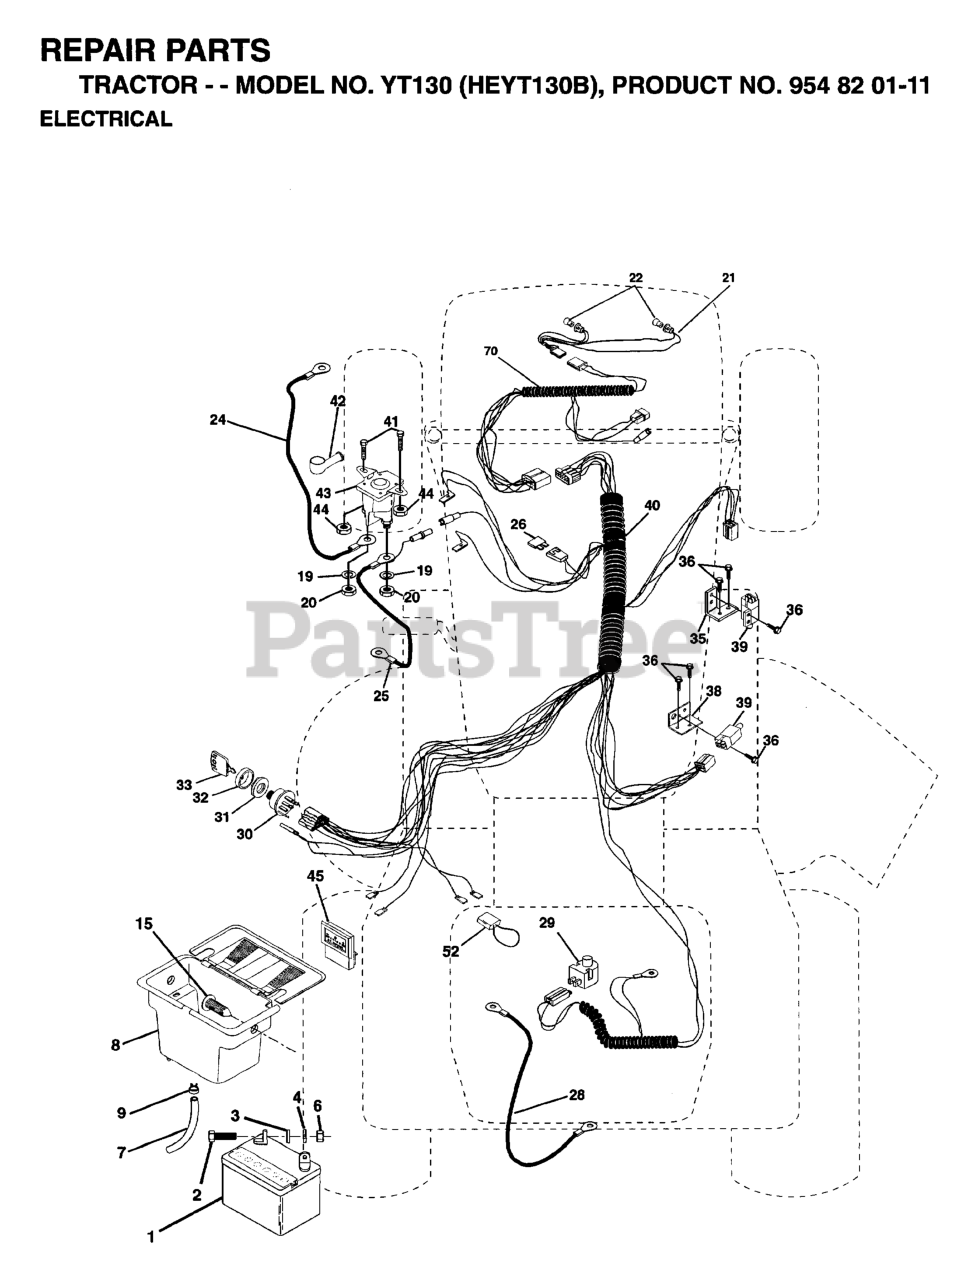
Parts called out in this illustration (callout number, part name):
1	BATTERY
2	BOLT.HEX.1/4.X.3/4.DICHROMATE
4	LOCKWASHER
6	NUT
7	TUBE BATTERY DRAIN
8	BATTERY CASE
9	HOSE CLAMP T
15	FASTERER SNAP-IN
19	LOCKWASHER
20	NUT
21	HARNESS LIGHT SOCKET
24	BATTERY CABLE GT
25	CABLE BATTERY
28	CABLE T
29	RP.SWITCH.PLUNGER.NC.GRAY
30	SWITCH.IGNITION.4.POSITION
31	NUT IGNITION
32	COVER SWITCH KEY
33	KEY.MOLDED.GENERIC
35	BRACKET LT
38	SWITCH BRACKET
39	SWITCH INTERLOCKT
40	HARNESS IGNITION
41	BOLT
42	TERMINAL COVER
43	SOLINOID
44	Nut, Keps Blk Hex 1/4-20 UNC
45	AMMETER
52	WIRE PROTECTION LOOP
70	ENGINE HARNESS
